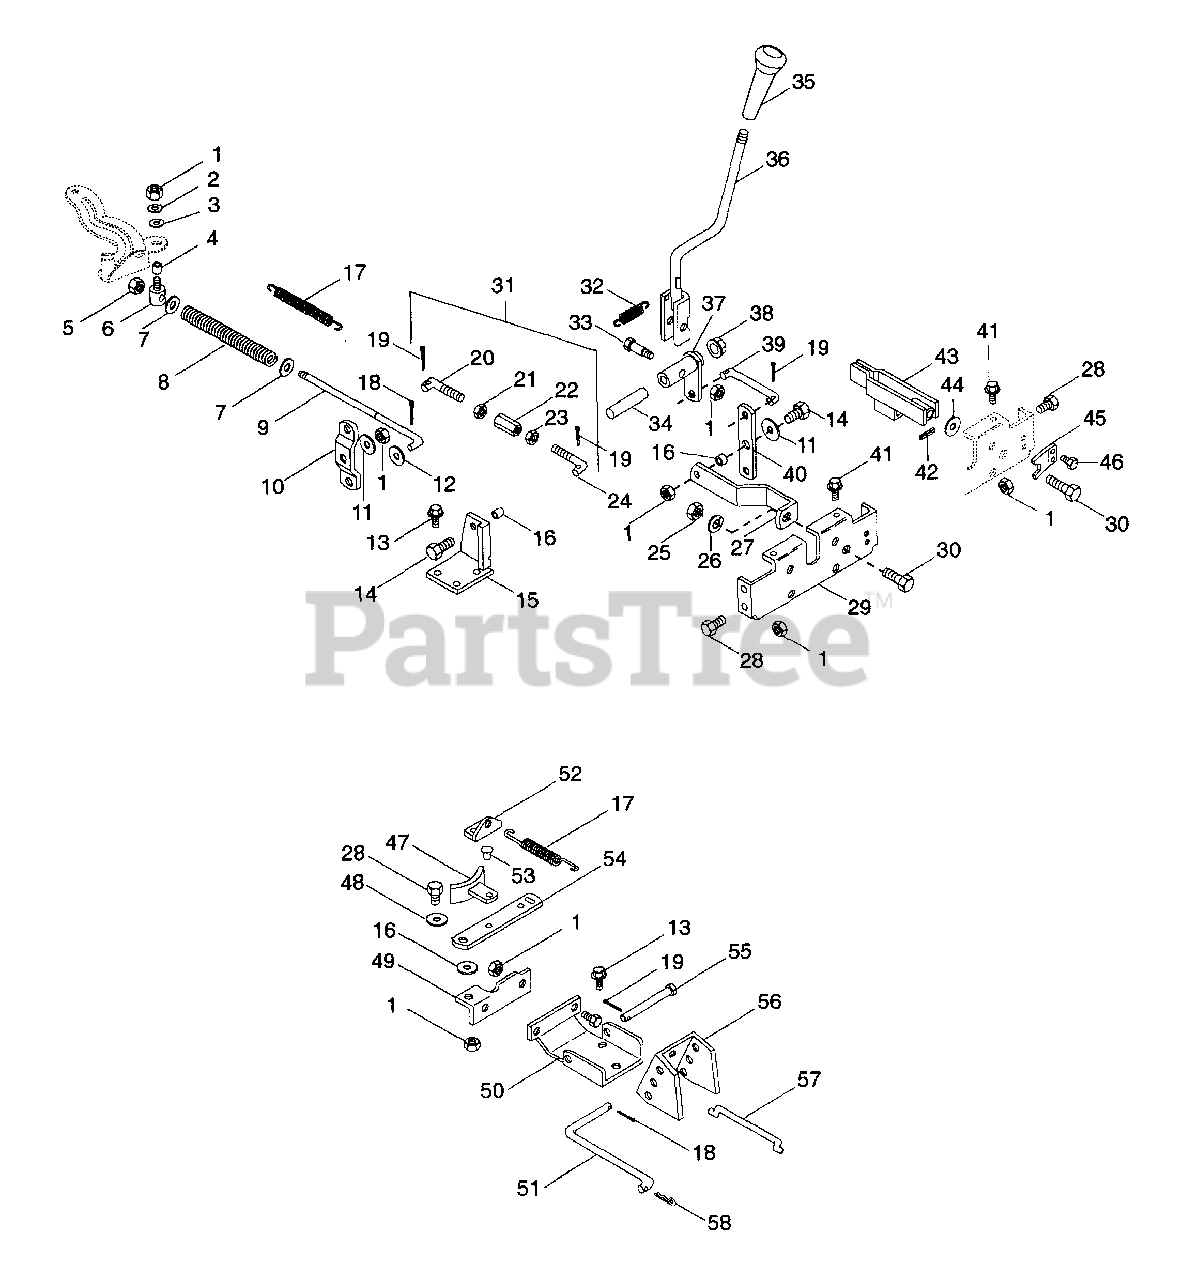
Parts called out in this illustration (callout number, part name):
1	NUT-LK .312-18 GR A PL
2	WSHR-FL-STL .323X.625X.062 PL
3	WAVE WASHER .531X.781X.125FH
4	SPACER BUSHING .5 X .32 X .21
5	NUT-LK-CTR .375-16 GR A PL
6	ROD PIVOT
7	WSHR-FL-STL .38X.875X.083 PL
8	SG-COMP .148X.68X6.5 WLD 90
9	CLUTCH ROD
10	ARM
11	WSHR-FL-STL .344X1.125X.063PL
12	WSHR-FL-STL.344X.688X.065PL
13	SCR-TAP .312-18X.50 HWH PL TR
14	BLT-HEX .31-18X.88 PL GR2
15	DECK PIVOT BRACKET
16	SPACER BUSHING .5 X .32 X .163
17	SG-TENS .072X.51X5.31 WLD 25
18	PIN-COTR .12X.75 PL
19	PIN-COTR .09X.75 PL
20	CLUTCH ROD RH
21	NUT-HEX .375-16
22	NUT-CUPLG RH & LH THD .37-16PL
23	NUT LH THD .375-16 GR 2 PL
24	CLUTCH ROD LH
25	NUT .50-13 PL
26	WSHR-LK .500X.151 HVY PL
27	FRONT ANCHOR
28	BLT-HEX .31-18X.63 PL GR 2
29	MOWER ADJUSTMENT BRACKET
30	CAP SCREW
30	BLT-HEX .50-13X1.25 PL GR2
31	CLUTCH ROD SERVICE ASSY
32	SG-TENS .092X.69X1.75 WLD 54
33	SHOULDER BOLT .436 X .912
36	MOWER CLUTCH LEVER
37	CLUTCH ARM
38	FLANGE BUSHING
39	LINK
40	CLUTCH LINK
41	SCR-TAP .250-20X.50 HXSLHDPL
42	PIN-ROLL .188X1.00
43	ADJUSTMENT YOKE
44	WSHR-FL-STL .505X1.000X.062
45	LOCK SPRING
46	SCR-TAP 10-24X.25 CRSLPH PL 1A
47	BLADE BRAKE
48	WSHR-FL-STL .328X1.0X.094
49	BRAKE BRACKET
50	PIVOT BRACKET
51	MOWER ENGAGEMENT LINK
52	BRAKE CLIP
53	RVT .25X.50 RH ST
54	MOWER BRAKE LEVER
55	PIN-CLEV .309X3.50 SP
56	MOWER ENGAGING ARM
57	MOWER BRAKE LINK
57	MOWER BRAKE LINK SERVICE ASSY
58	PIN-HAIR INT .08X.38X1.42 YWZC
